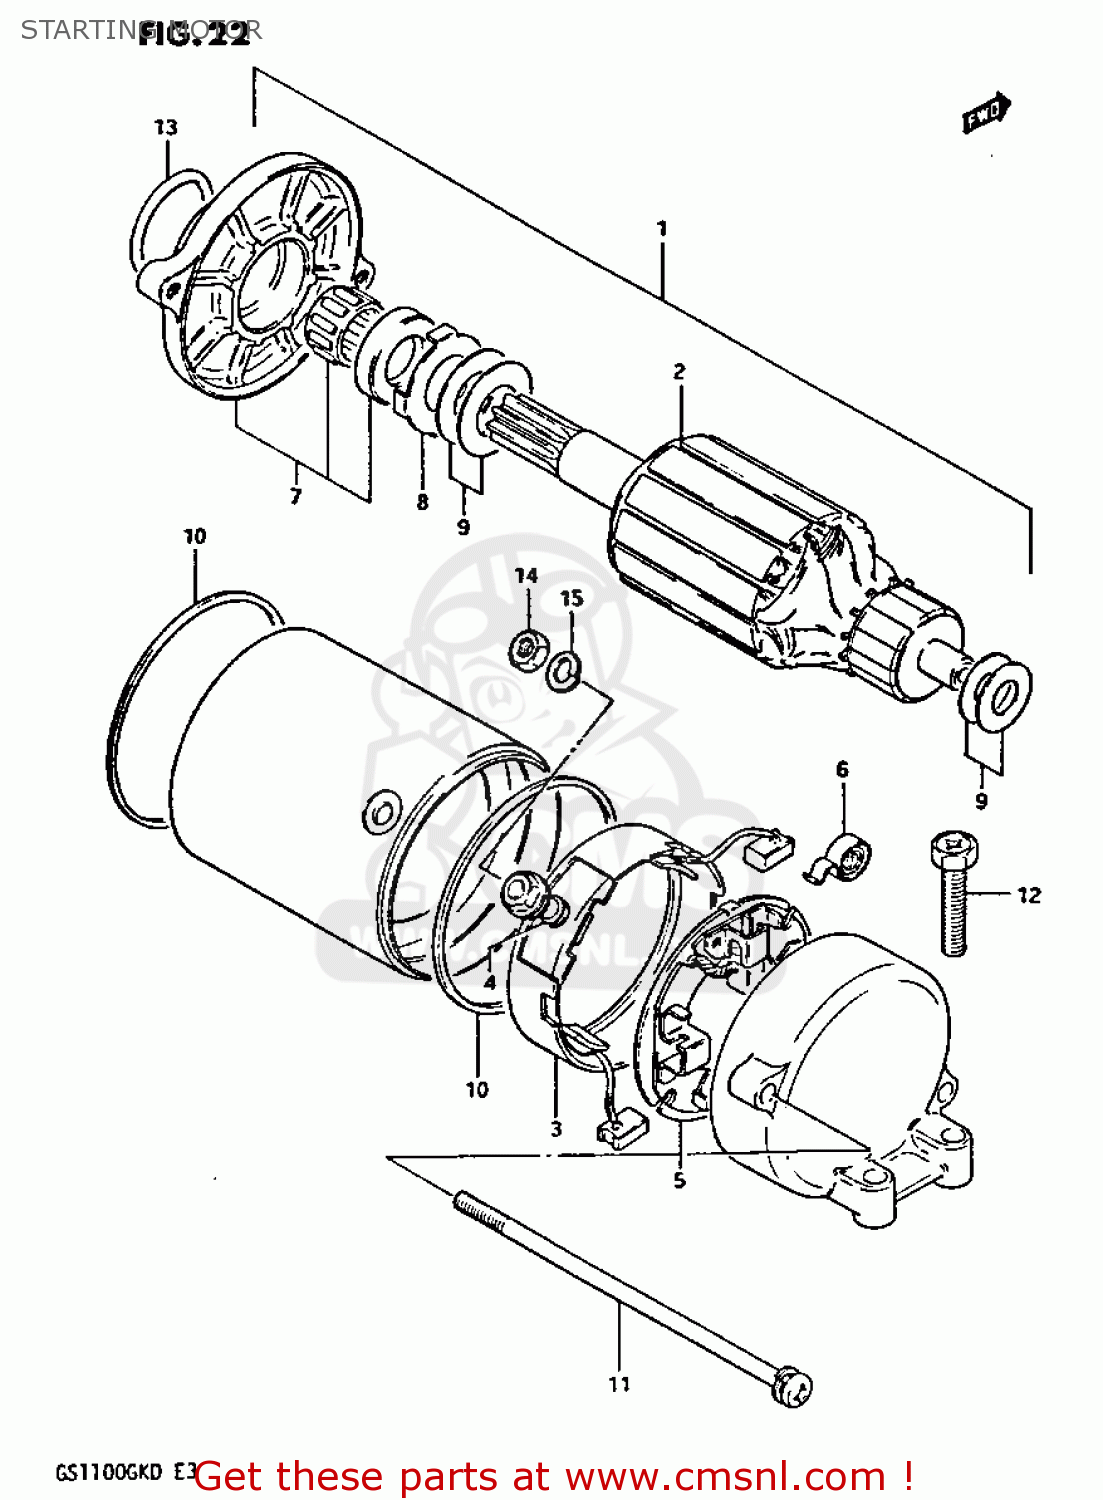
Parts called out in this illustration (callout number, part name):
1	MOTOR ASSY,STARTING
2	ARMATURE
3	BRUSH TERMINAL SET
4	O RING
5	HOLDER,BRUSH
6	SPRING,BRUSH
7	HOUSING SET,STARTING MOTOR
8	SHIM SET
9	SHIM SET
10	SEAL,RING
11	BOLT,STARTING MOTOR HOUSING
12	SCREW (6X25)
13	O RING(D:3,ID:24.5)
14	NUT 6MM
15	WASHER,LOCK
